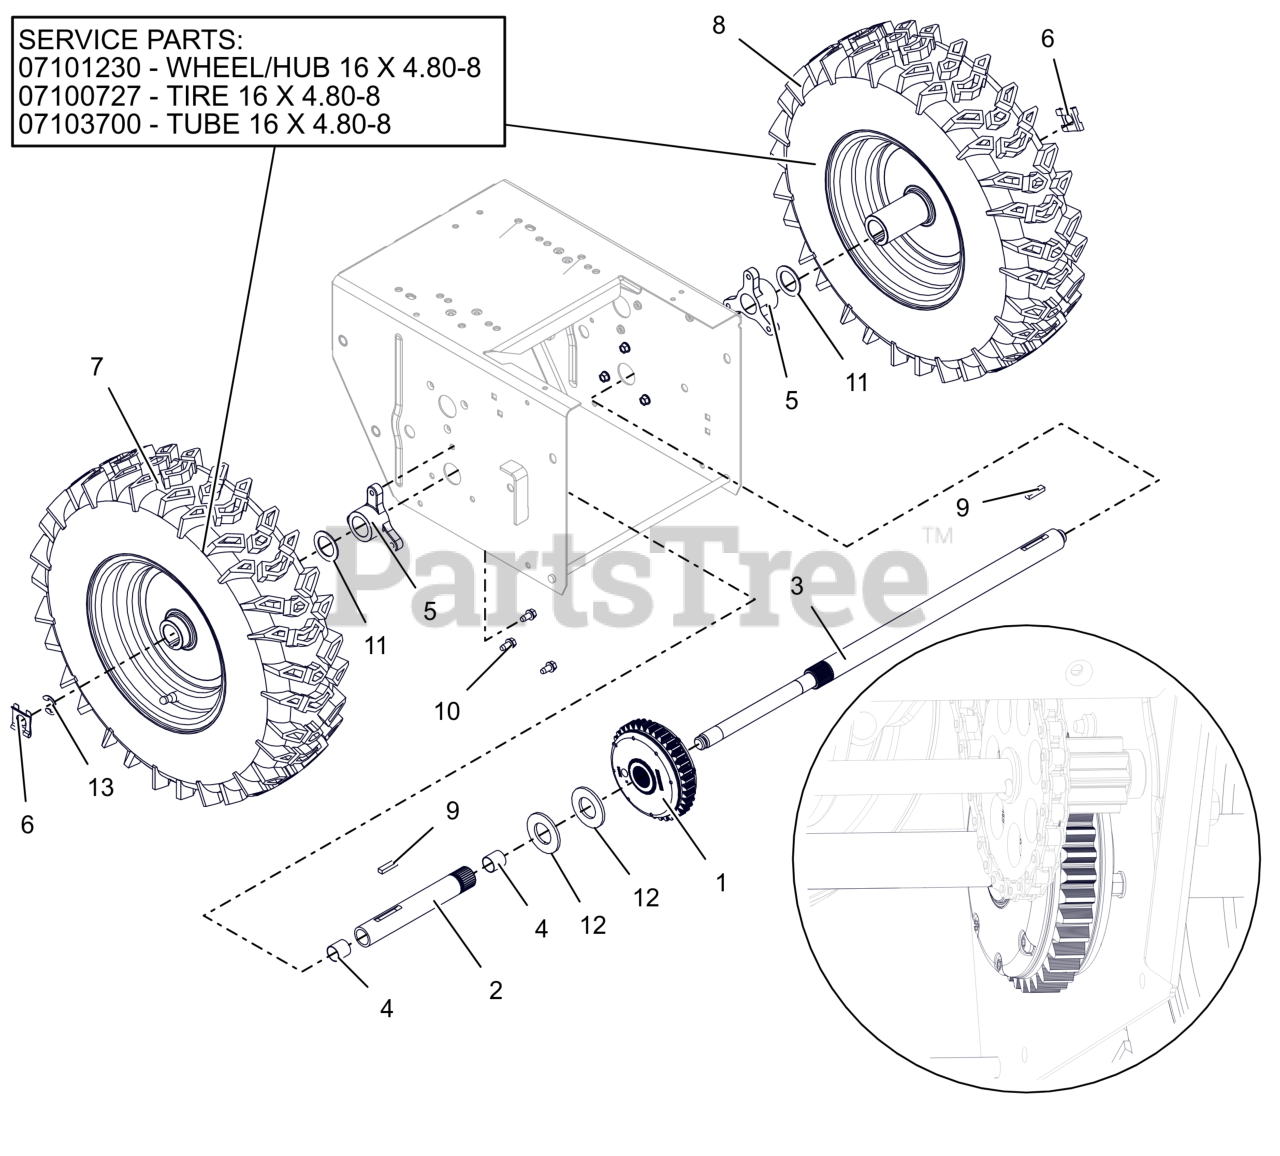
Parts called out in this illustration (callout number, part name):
1	DIFFERENTIAL, AUTOMATIC
2	AXLE, SHORT - W/BUSHINGS
3	AXLE,LONG-DELUXE AUTO DIFF
4	BSHG-SLV .706X.764X.75 BRZ
5	BUSHING, AXLE
6	CLIP, SNAP .625 DIA
7	TIRE/WHEEL,RH 16X4.8-8 DIFF T2
7	HUB, WHEEL-16X4.8-8
7	TIRE, 4.80-8 K478
7	TUBE
8	TIRE/WHEEL,LH 16X4.8-8 DIFF T2
8	HUB, WHEEL-16X4.8-8
8	TIRE, 4.80-8 K478
8	TUBE
9	KEY-RECT .25X.188X1.00
10	SCR-TAP .25-20X.50 HWH ZCC
11	WSHR, FLT 1.010X1.505X.062 ZCC
12	WSHR, FLT 1.062X2.000X.134 ZCC
13	RG-RTNG-EXT .625X.042
